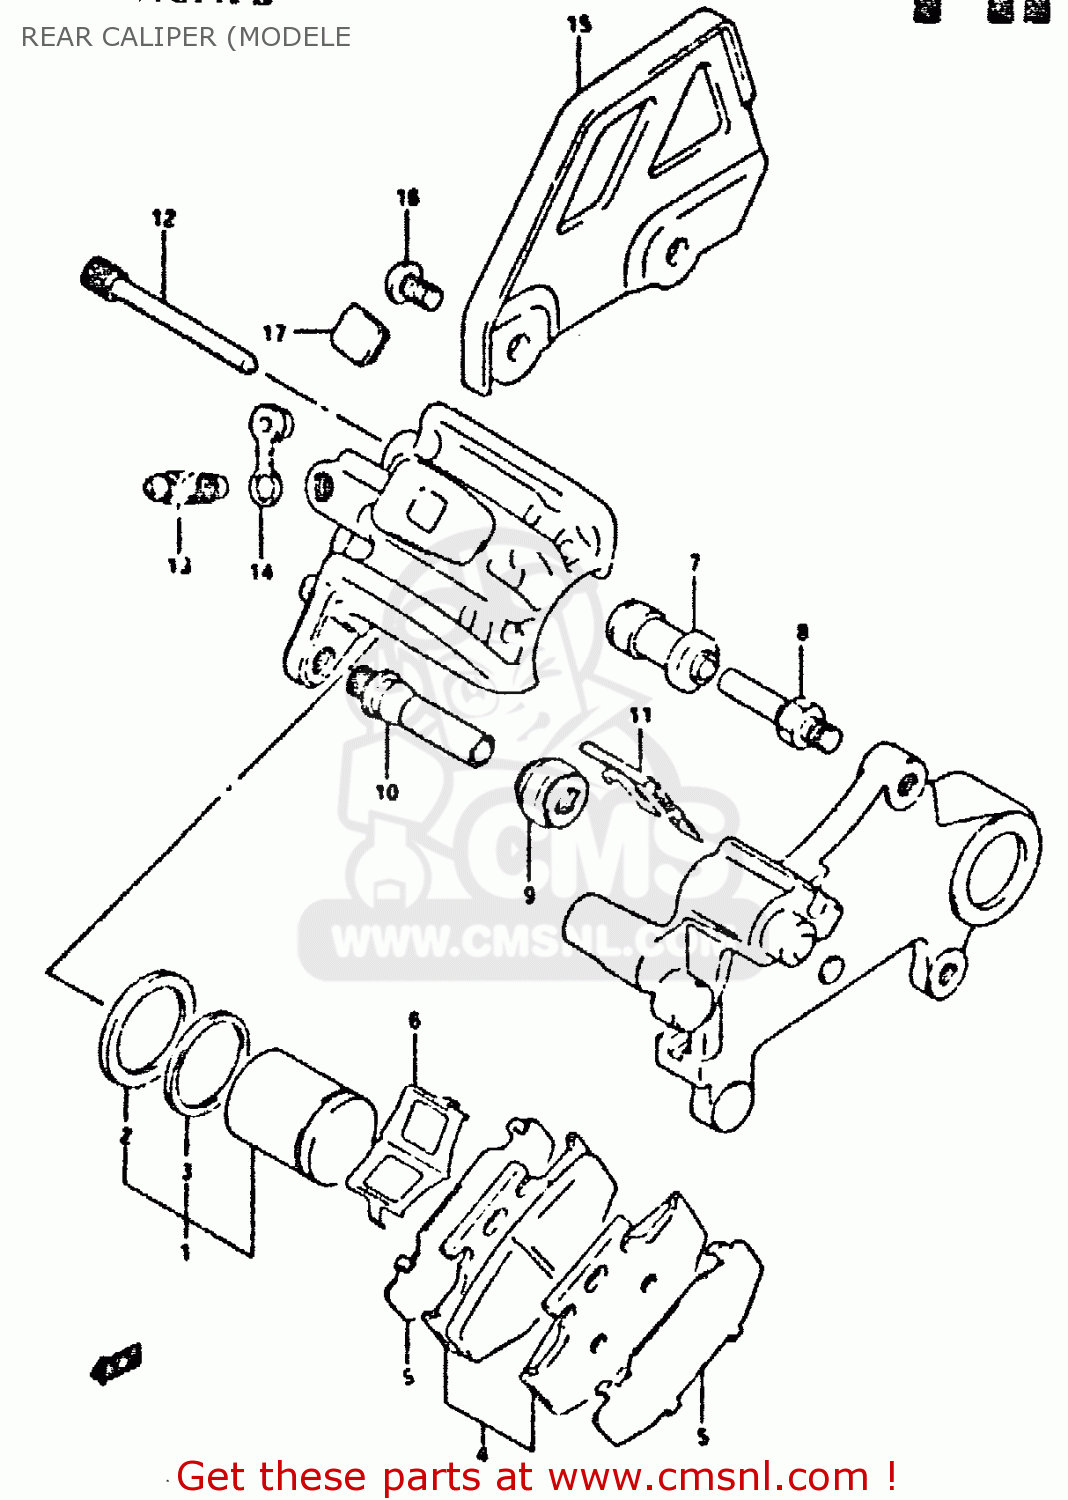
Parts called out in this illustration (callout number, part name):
1	PISTON SET
2	SEAL,PISTON
3	SEAL,DUST
4	PAD SET (NAS)
5	SHIM
6	SPRING,PAD
7	BOOT
8	PIN,BOLT
9	BOOT
10	PIN
11	RETAINER,BRACKET
12	PIN,HANGER
13	BLEEDER
14	CAP,BLEEDER
15	GUARD,RR CALIPER
16	SCREW 6X12
17	BOLT
18	COVER,RR CALIPER BODY
